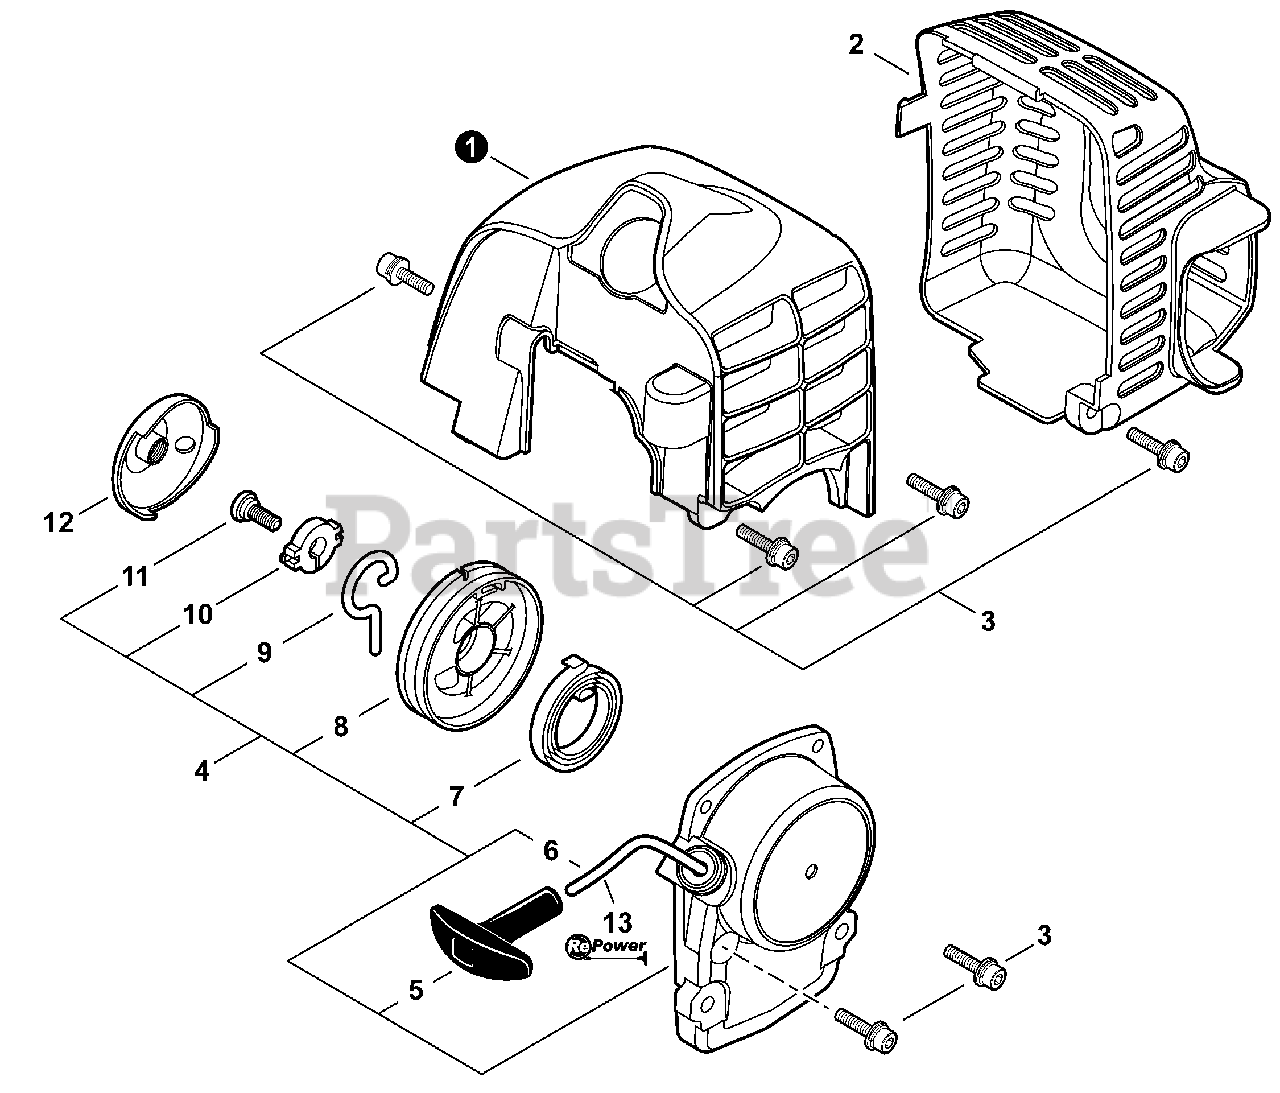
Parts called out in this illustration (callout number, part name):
1	COVER, ENGINE
2	COVER, MUFFLER
3	BOLT M4×16
4	STARTER ASSY, RECOIL
5	GRIP, STARTER
6	ROPE, STARTER Ø3×850
7	SPRING, RECOIL
8	REEL, ROPE
9	ARM, SWING
10	WASHER 5
11	SCREW 5
12	PULLEY, STARTER
13	ROPE, STARTER - REPOWER BULK Ø3
